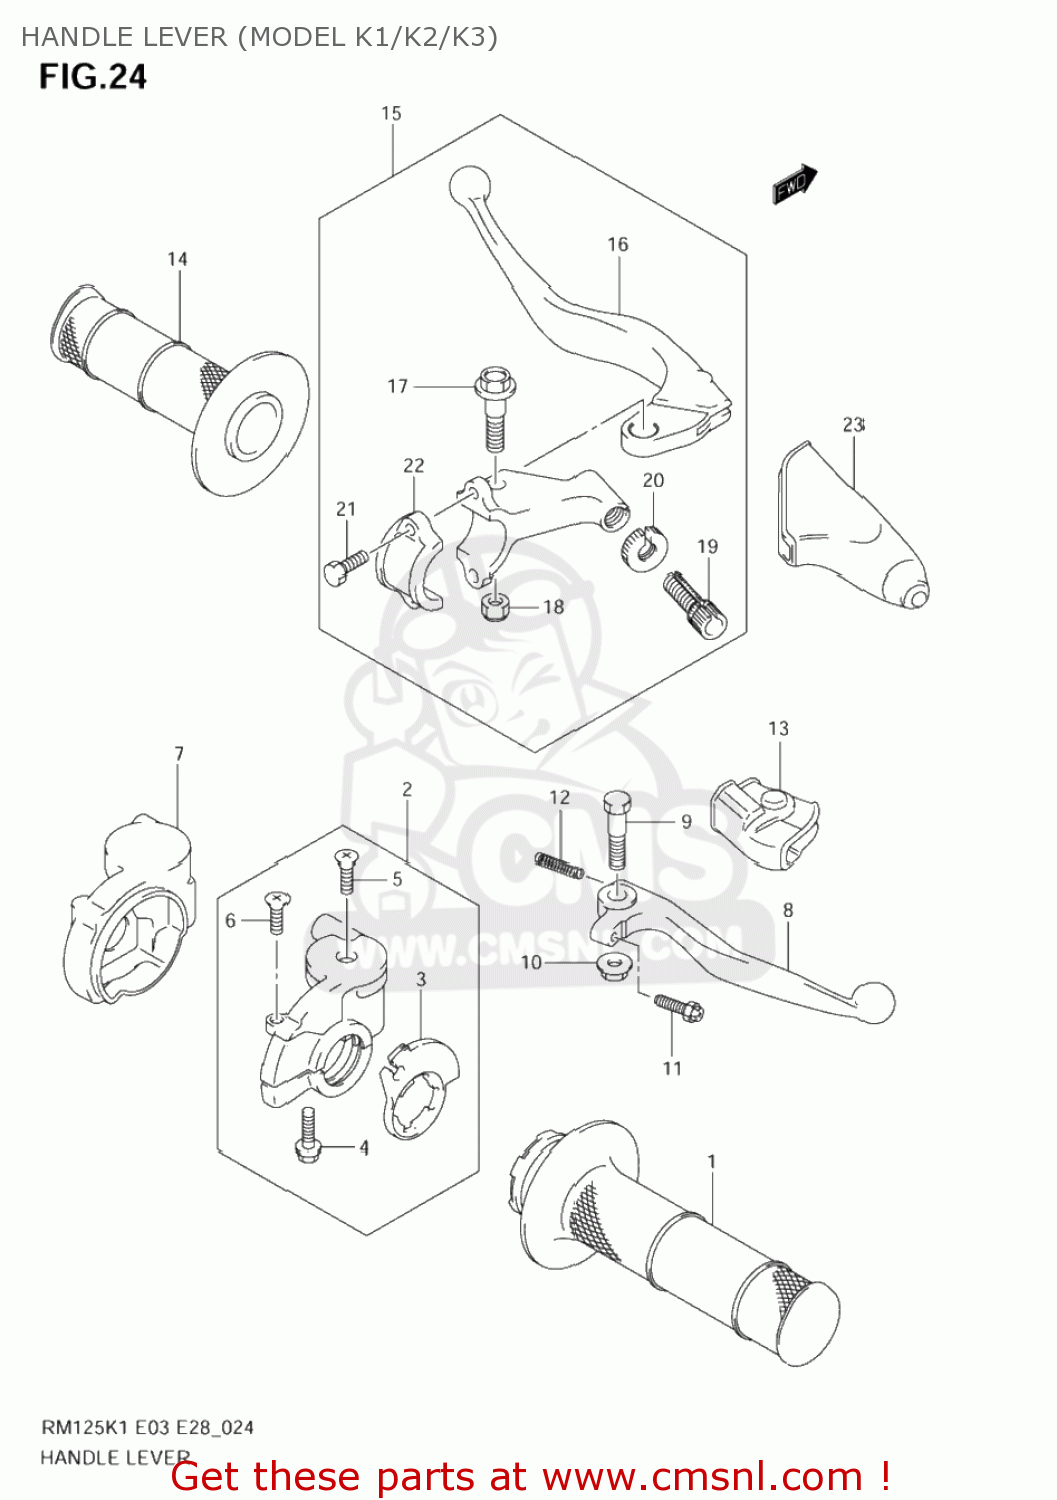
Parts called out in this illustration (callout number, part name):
1	GRIP,THROTTLE
2	CASE ASSY,THROTTLE
3	ROTOR,THROTTLE
4	SCREW
5	SCREW,UPPER
6	SCREW
7	COVER,THROTTLE CASE
8	LEVER,BRAKE
9	BOLT,BRAKE LEVER
10	NUT
11	BOLT,ADJUSTER
12	SPRING,RETURN
13	COVER,BRAKE LEVER
14	GRIP,L
15	LEVER ASSEMBLY,CLUTCH
16	LEVER,CLUTCH
17	BOLT,LEVER
18	NUT 6MM
19	ADJUSTER,WIRE
20	NUT,LOCK
21	BOLT
22	BRACKET,CLUTCH LEVER HOLDER
23	COVER,CLUTCH LEVER
